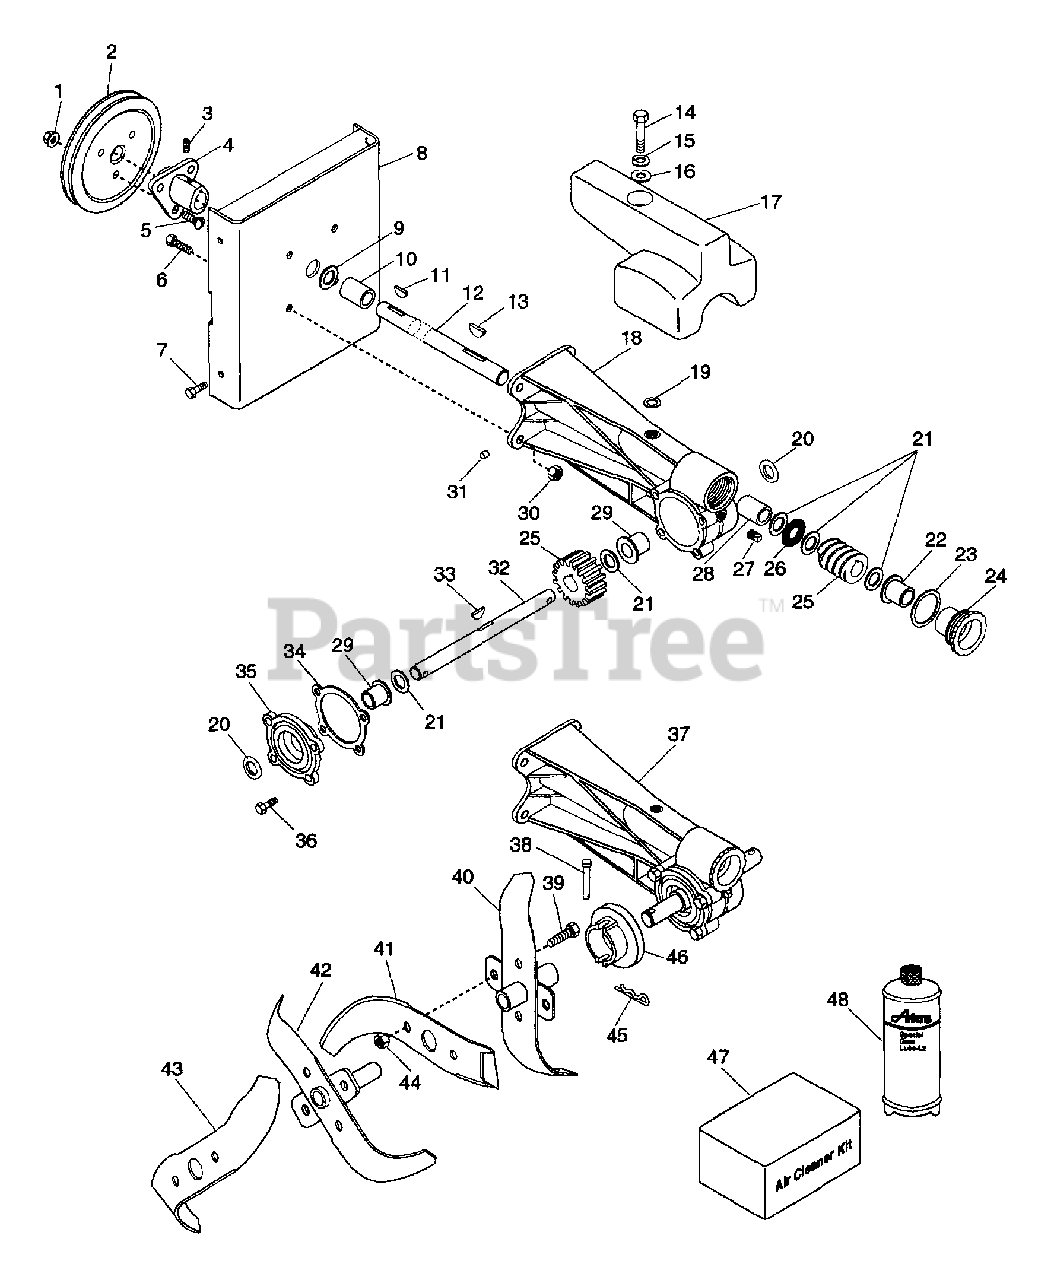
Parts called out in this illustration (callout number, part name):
1	NUT-FLG. .312-18 PL
2	PLY-V 8.50 X 1.25 3BLT
3	SCR-SET .32-18X.38 SKHCUPNL OH
4	HUB
5	BLT-SERRDHD SL .31-18X.75 YZ
6	SCREW - FLG WIZ LOCK HH PL
7	BLT-SERHFWH .31-18X.50 PL
8	TILLER MOUNTING PLATE
9	SEAL .750X1.000X.125
10	BSHG-SLV .750X1.000X1.000
11	KEY-WDRF .188X.875X.375 SAE11
12	WORM SHAFT
13	KEY-FTHR .188X1.38X.188
14	BLT-HEX .38-16X2.25 GR2
15	WSHR-LK .375X.094 MED PL
16	WSHR-FL-STL.406X.812X.065PL
17	TILLER WEIGHT
18	GEARCASE
19	SHIM SPACER
20	SEAL .750X1.980X.375
21	WSHR-HDND-THRST .755X1.40X.062
22	BSHG-FLG .750X1.000X.750X1.132
24	ADJUSTMENT PLUG
25	WORM & WORM GEAR ASSEMBLY
26	BRG-N THRST .754X1.24X.078
27	PIPE PLUG
28	BSHG-SLV .750X1.000X.750
29	BSHG-FLG .750X1.250X.750X1.375
30	NUT-LK-FLG .375-16 PL
31	BREATHER
32	TINE SHAFT
33	KEY-WDRF .188X.625X.25 SAE 61
36	BLT-SERHFWH .31-18X.75 PL
37	TILLER GEARCASE - ALUMINUM
38	PIN, CLEVIS .243/.248X1.50 YWZ
39	BLT-HEX .31-18X.75 PL GR2
40	R H INNER TINE SPOOL
40	L H INNER TINE SPOOL
41	R H INSIDE TINE
41	L H INSIDE TINE
42	R H OUTER TINE SPOOL
42	L H OUTER TINE SPOOL
43	R H OUTSIDE TINE
43	L H OUTSIDE TINE
44	NUT-LK .312-18 GR A PL
45	PIN-HAIR INT .08X.18X1.18
46	DUST CAP
47	AIR CLEANER KIT
48	ARIENS 16 OZ.BOTTLE OF L2 LUBE
